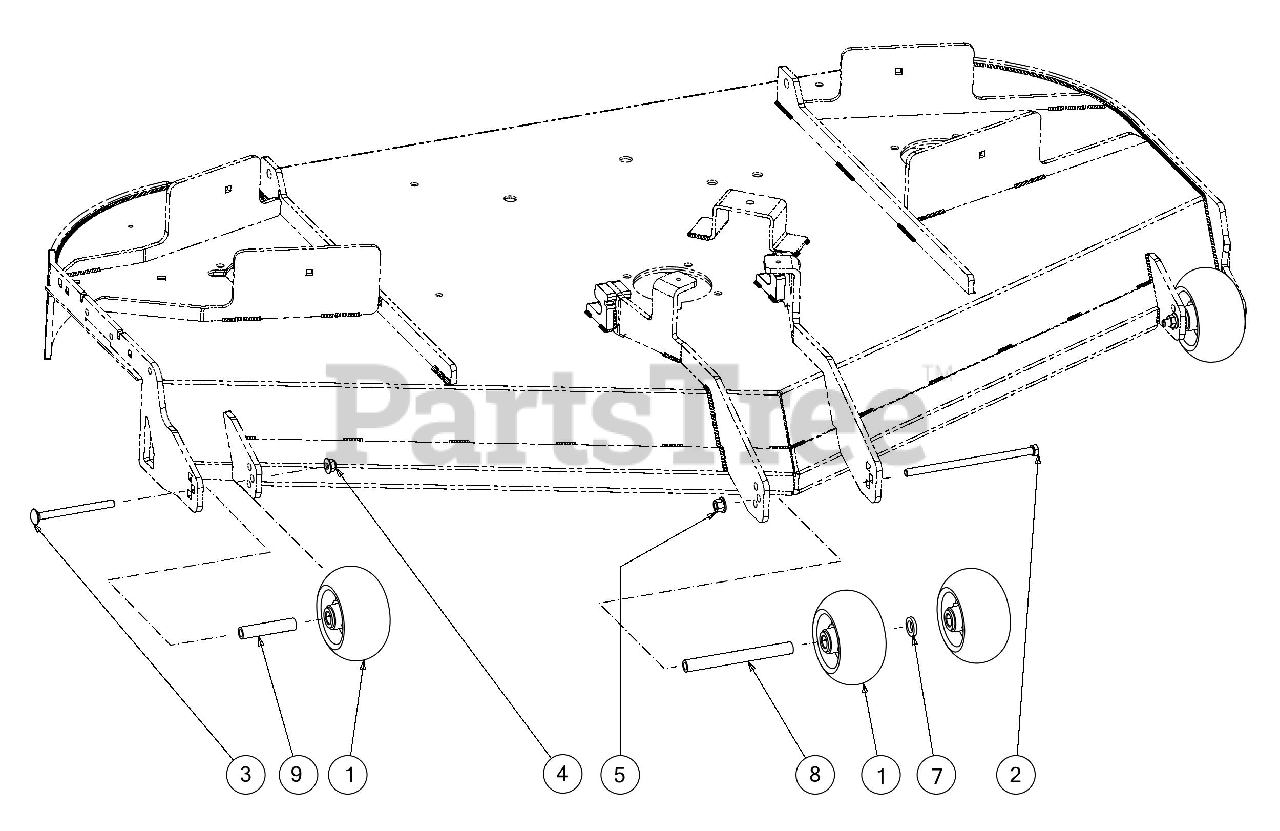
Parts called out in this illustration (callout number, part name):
1	WHEEL ASSEMBLY 5"
2	SCREW 3/8-16 X 7.25 GR5
3	CARRIAGE BOLT 3/8-16 X 4.25 GR5
5	NUT-CTRLCK FLG HEX
6	FLAT WASHER
7	FLAT WASHER .632X1.00X.16
8	WHEEL SPACER
9	WHEEL SPACER .38ID X 3.04LG
